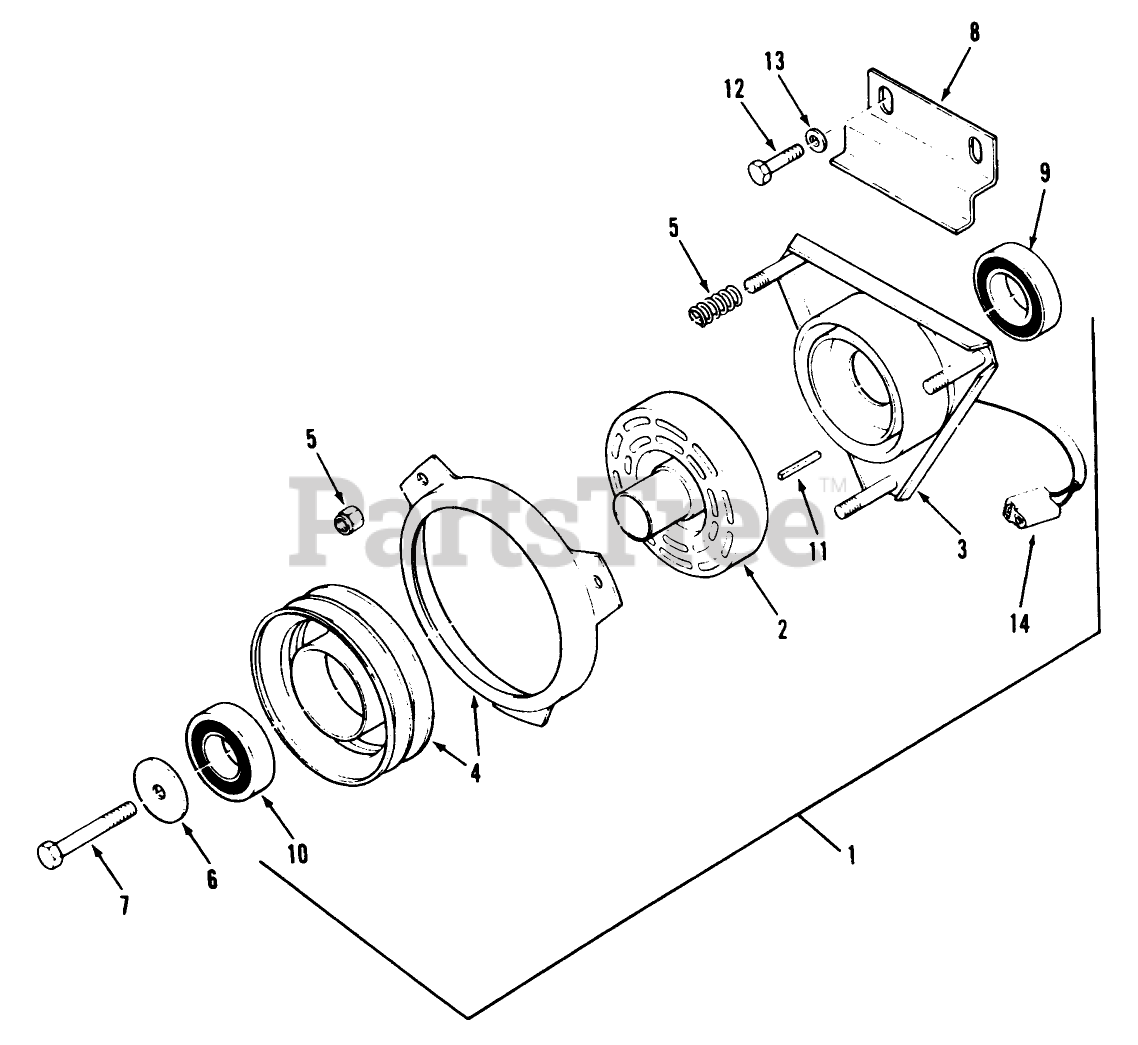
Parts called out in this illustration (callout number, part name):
3	FIELD-ASS'Y
5	ACCESS SPRING & NUT
6	RETAINER-BEARING
7	SCREW-HH
8	BRACKET-CLUTCH *B
9	BEARING-FIELD ASS'Y
10	BEARING-ELEC CLUTCH
11	KEY-SQUARE
12	SCREW-HH
13	WASHER-FLAT
14	CONNECTOR BODY *B
